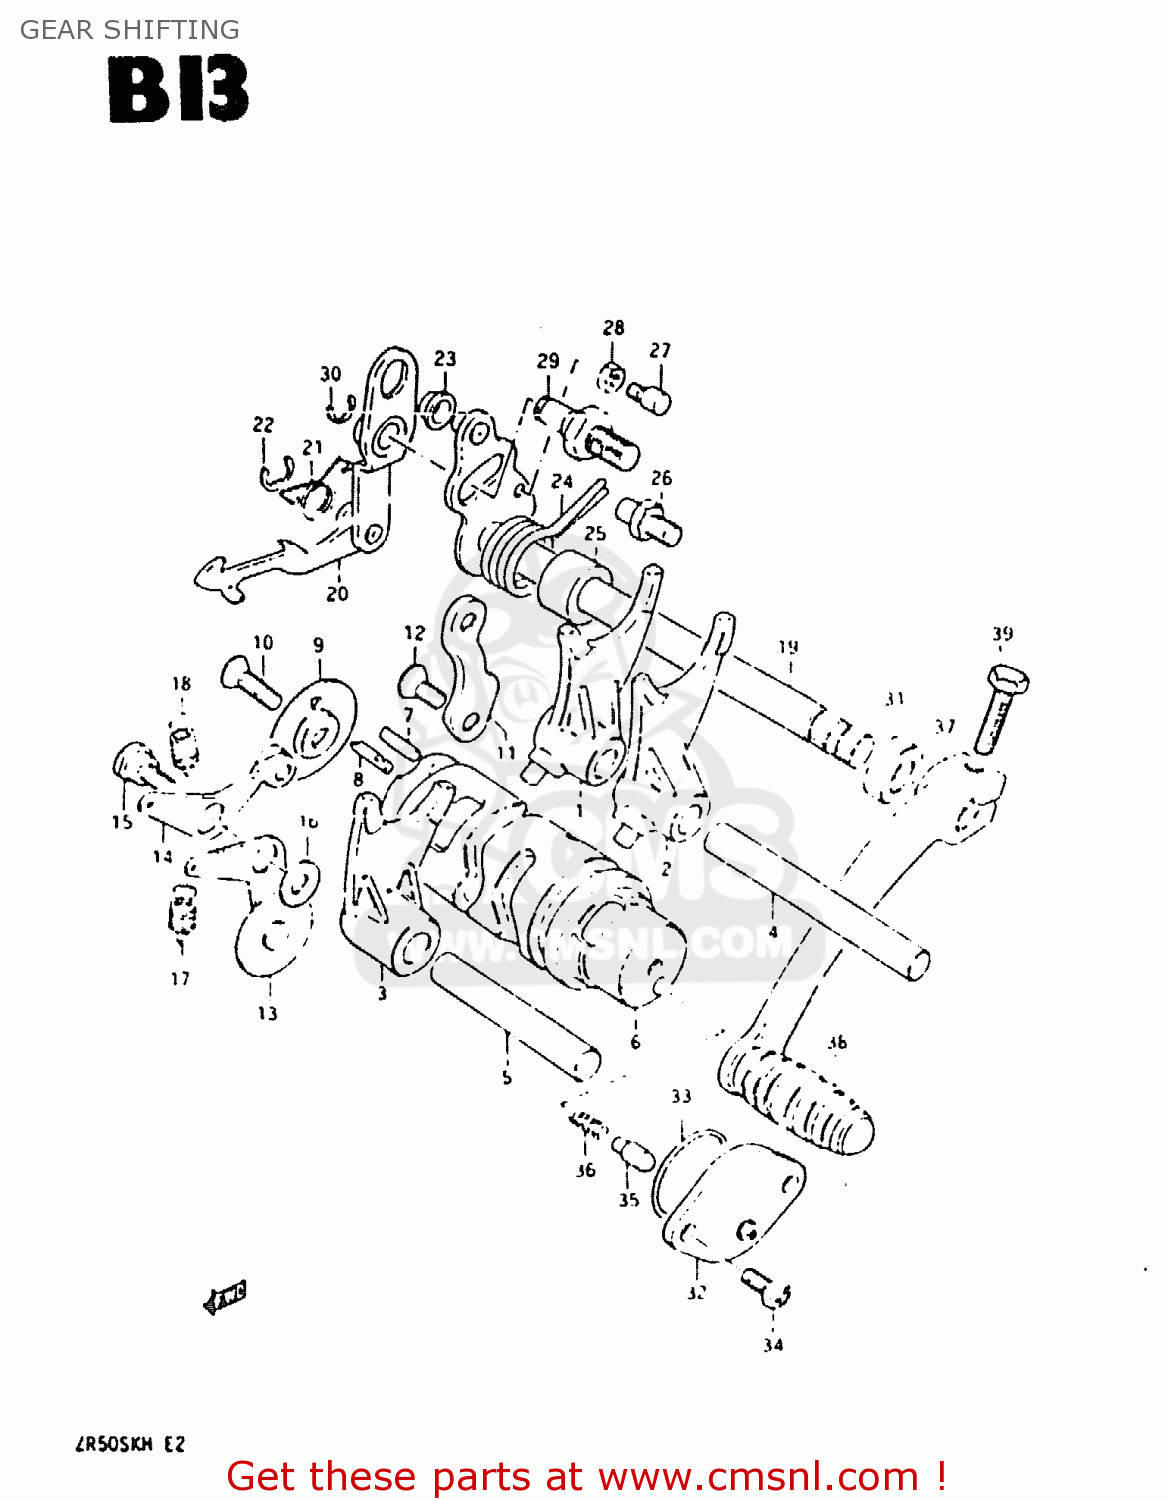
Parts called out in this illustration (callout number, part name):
1	FORK,GEAR SHIFT NO.1
2	FORK,GEAR SHIFT NO.2
3	FORK,GEAR SHIFT NO.2
4	SHAFT,GEAR SHIFT FORK
5	SHAFT,GEAR SHIFT FORK
6	CAM,GEAR SHIFT
7	PIN(4X15.8)
8	PIN
9	RETAINER,GEAR SHIFT CAM DR PIN
10	SCREW
11	GUIDE,GEAR SHIFT CAM
12	SCREW
13	STOPPER,GEAR SHIFT CAM
14	STOPPER,GEAR SHIFT CAM NEUTRAL
15	BOLT(6X18.3)
16	WASHER
17	SPRING
18	SPRING
19	SHAFT,GEAR SHIFT
20	PAWL,GEAR SHIFT
21	SPRING
22	E RING
23	SPACER(7X10X5)
24	SPRING
25	SPACER(12X20X15.3)
26	STOPPER,GEAR SHIFT CAM
27	BOLT,GEAR SHAFT RETURN SPR SET
28	NUT 6MM
29	STOPPER,GEAR SHIFT CAM
30	E RING 6MM
31	OIL SEAL
32	BODY,GEAR SHIFT SWITCH
33	O-RING (D:2.4 ID:26.2)
34	SCREW
35	PIN(5X15.5)
36	SPRING
37	LEVER ASSEMBLY,GEAR SHIFTING
38	RUBBER,GEAR SHIFT PEDAL
39	BOLT
